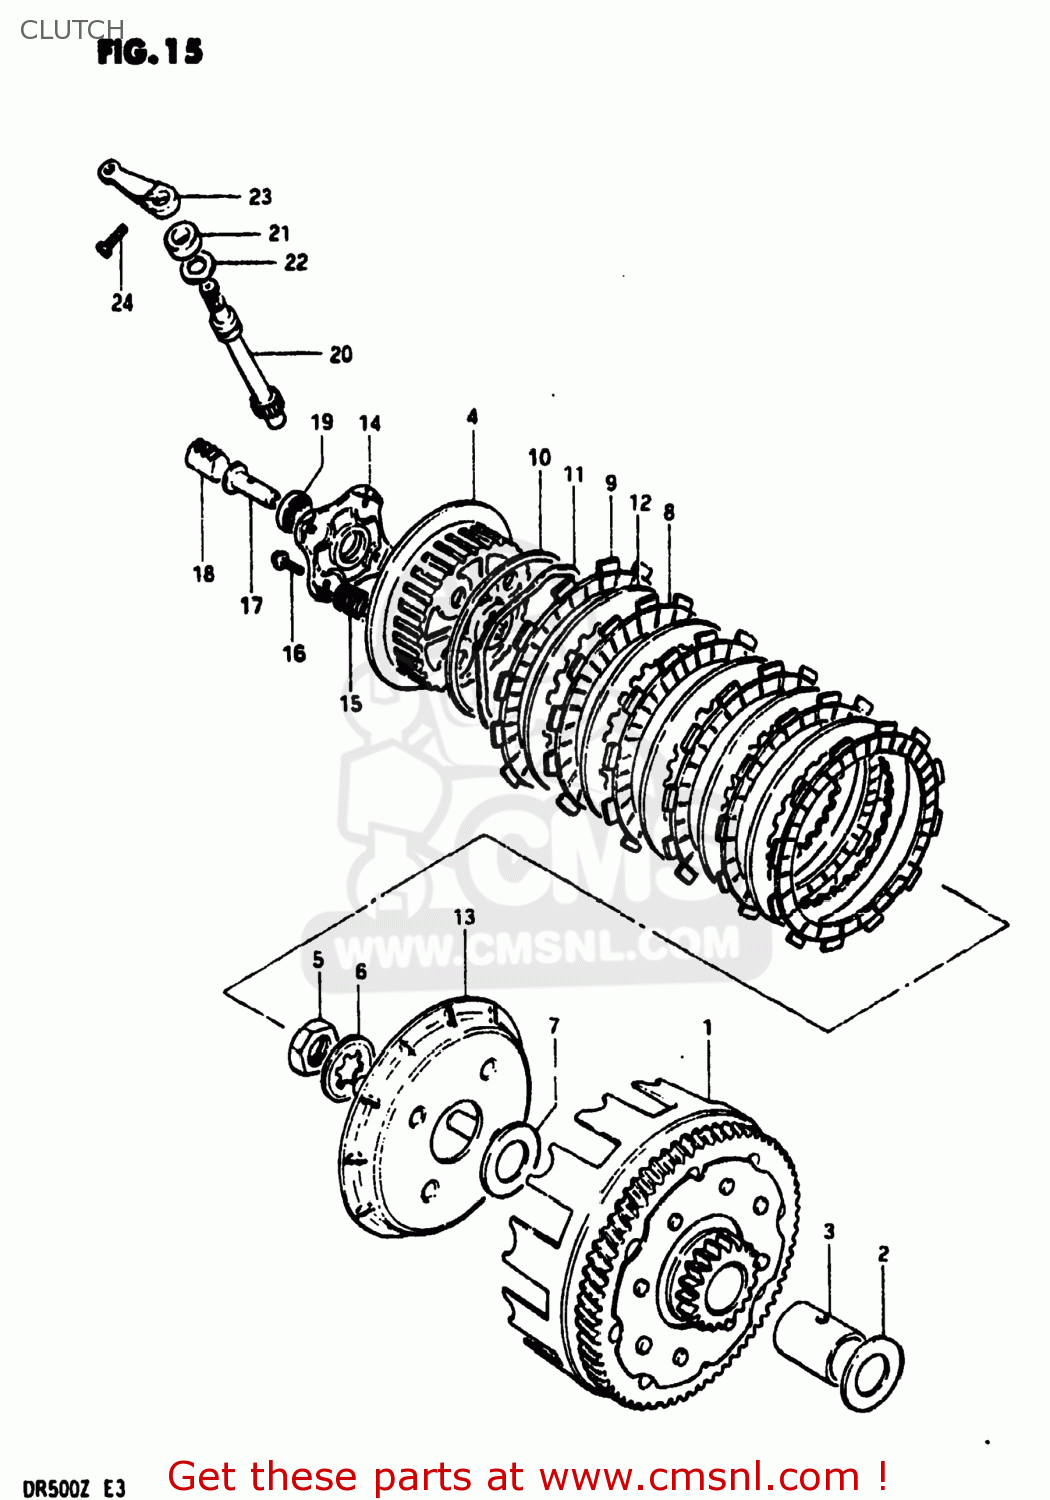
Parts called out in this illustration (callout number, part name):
1	GEAR ASSEMBLY,PRIMARY DRIVE
2	WASHER
3	SPACER(22X28X32.5)
4	HUB,CLUTCH SLEEVE
5	NUT
6	WASHER,LOCK
7	WASHER
8	PLATE,CLUTCH DRIVE (NAS)
9	PLATE,CLUTCH DRIVE
10	SEAT,WAVE WASHER(T:1.4)
11	WASHER
12	PLATE,CLUTCH DRIVEN
13	DISC,CLUTCH PRESSURE
14	PLATE,RELEASE
15	SPRING
16	BOLT,REAR
17	PIECE,CLUTCH PUSH
18	RACK,CLUTCH RELEASE
19	BEARING
20	PINION,CLUTCH RELEASE
21	OIL SEAL
22	WASHER (14.2X22X1)
23	ARM,CLUTCH RELEASE
24	BOLT
